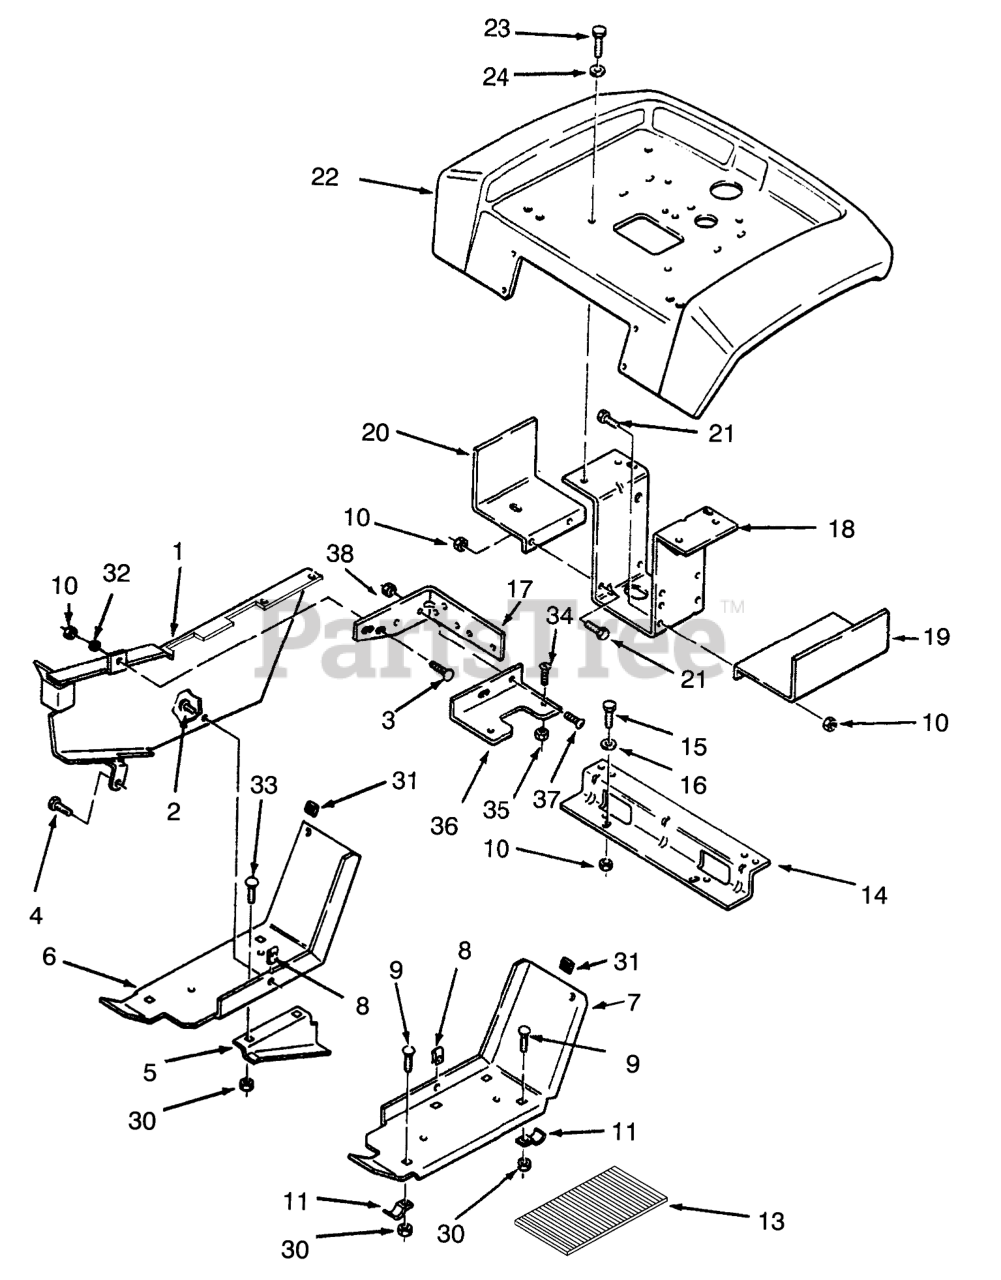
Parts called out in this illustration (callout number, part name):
1	Belt Guard
2	SCREW-PPH
3	BOLT-CARR
4	Bolt
5	GUID-LOWER BLTR
6	Footrest-RH
7	FOOTREST LH R
9	BOLT-CARR
10	NUT-LOCK, NI
11	BRACKET
13	PAD FOOTREST
14	BRACKET-FENDER B
15	SCREW-HH
16	WASHER-PLAIN
17	BRACKET-BELTB
18	Bracket-Fender
19	Fuel Tank Support LH
20	Support-FueITank RH
21	SCREW-HH
22	Fender
23	Bolt
24	WASHER 5/16 SAE
30	NUT-LOCK, NI
31	BUMPER SJ5514 BLACK
32	NUT-PUSH
33	BOLT-CARR 5/16 SN
34	SCREW-PAN
35	Nut
36	FUSE HOLDERB
37	SCREW-HH
38	NUT-LOCK, NI
